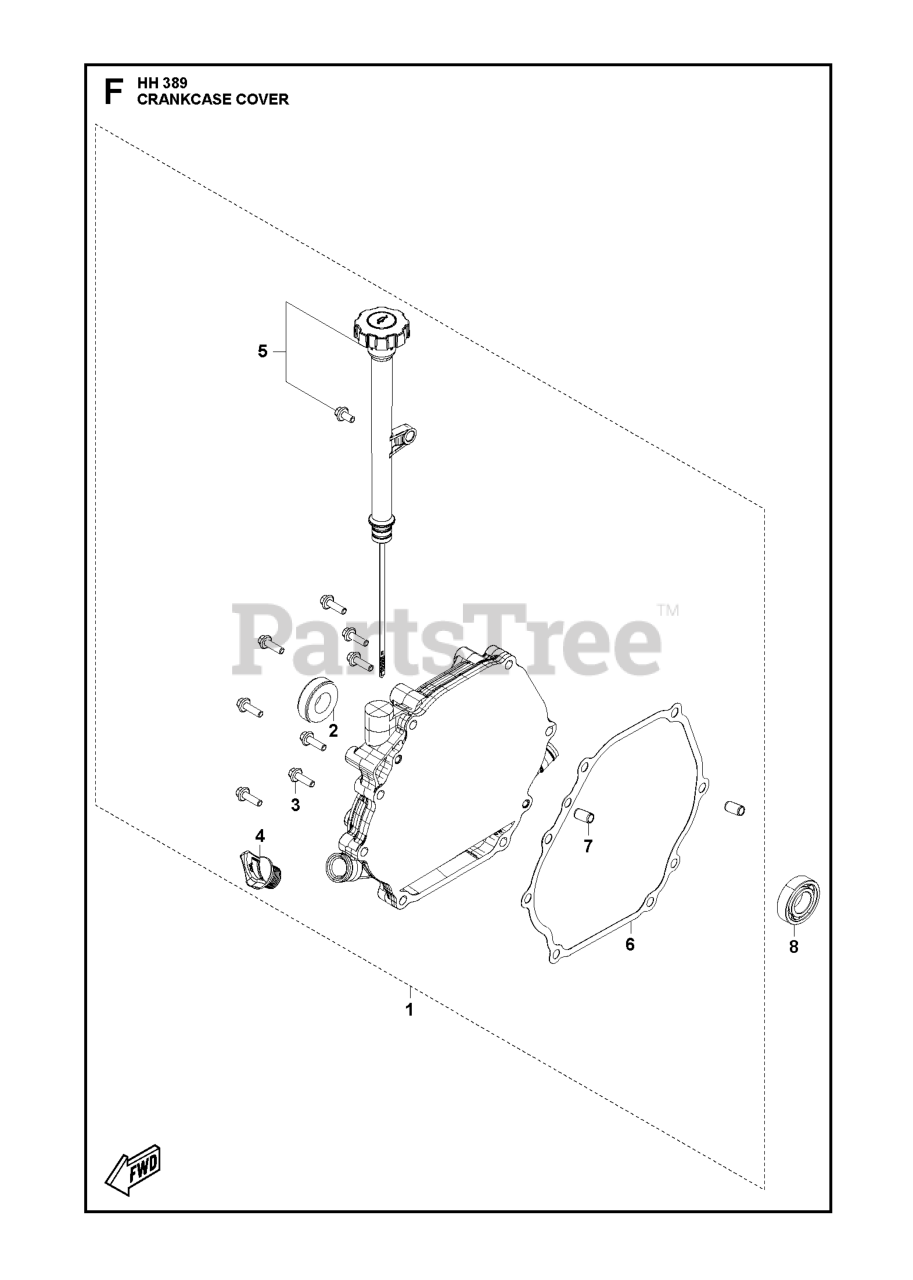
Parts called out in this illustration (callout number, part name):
1	COVER KIT CRANKCASE COVER
2	SEAL OIL SEAL
3	BOLT
5	DIPSTICK DIPSTICK KIT
6	GASKET CRANKCASE COVER GASKET
7	PIN LOCATION PIN
8	BALL BEARING
